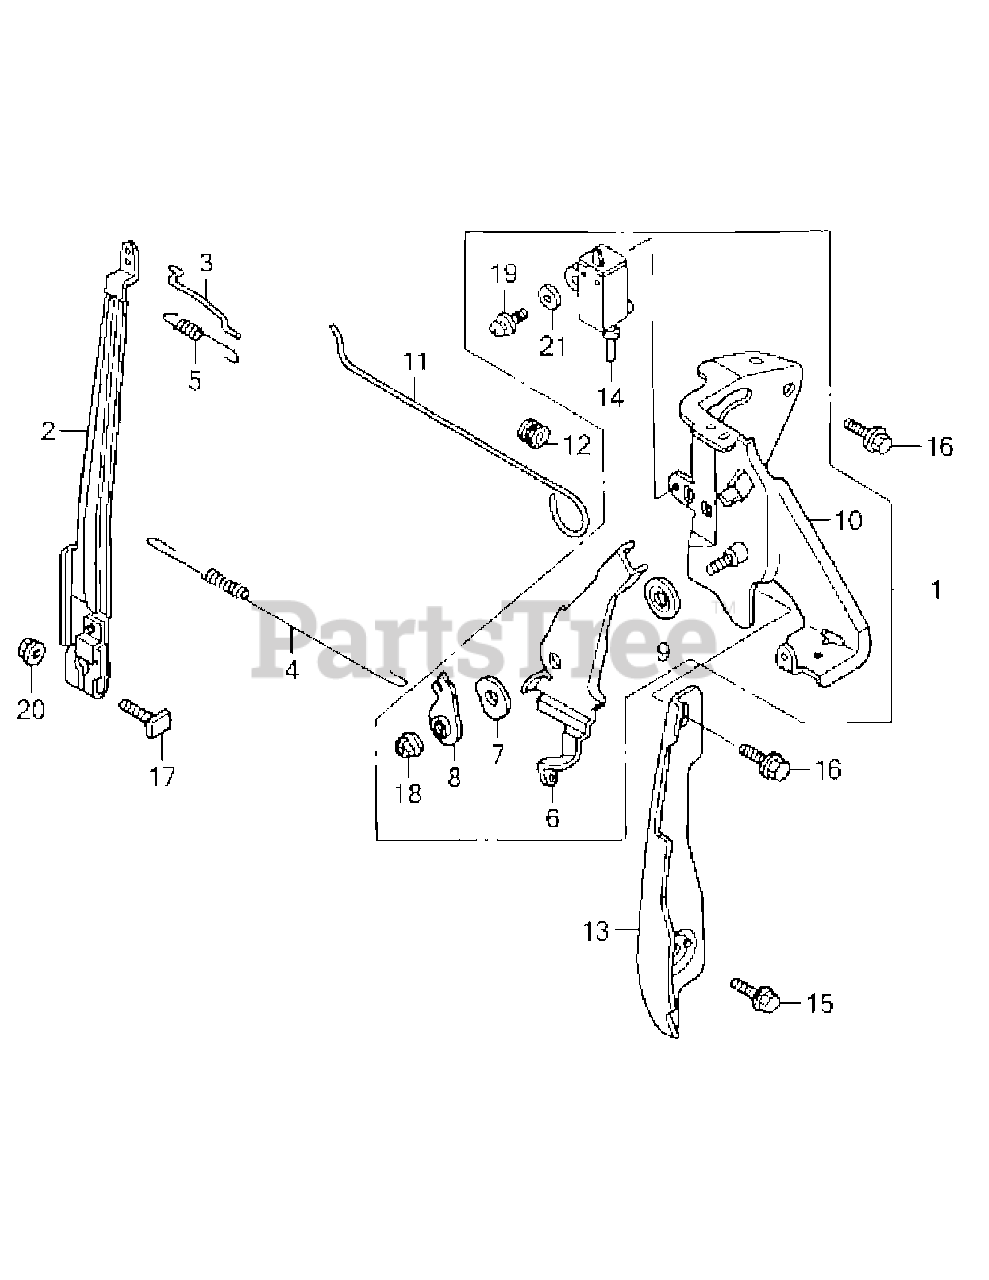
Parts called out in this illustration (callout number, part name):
1	Control Assy.
2	Arm, Governor
3	Rod, Governor
4	Spring, Governor
5	Spring, Throttle Return
6	Lever, Control
7	Spring, Lever
8	Washer, Control Lever
9	Spacer, Control Lever
10	Base Comp., Control
11	Rod, Choke Control
12	Grommet, Choke Rod
13	Plate, Side
14	Switch Assy., Engine Stop (N.O)
15	Bolt, Flange, 6X12 (Ct200)
16	Bolt, Flange, 6X14 (Ct200)
17	Bolt, Governor Arm
18	Nut, Self-Lock, 6Mm
19	Screw-Washer, 4X12
20	Nut, Flange, 6Mm
21	Washer, Plain, 4Mm
